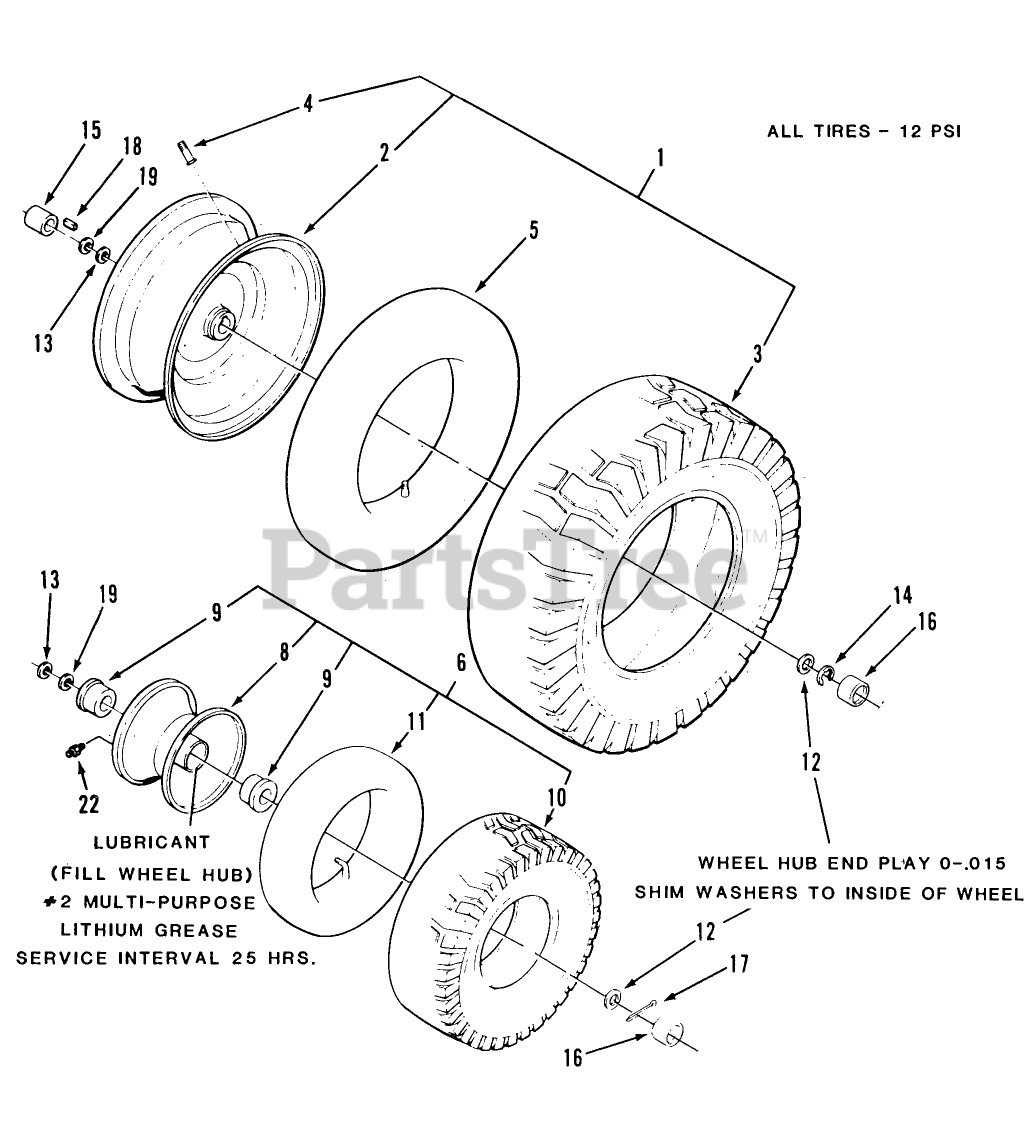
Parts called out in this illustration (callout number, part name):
4	VALVE
6	ASSY-WHEEL TIRE
8	ASS'Y-WHEEL
9	BUSHING-FLANGE
12	WASHER-FLAT
13	WASHER
15	LH AXLE SPACER
18	SQ KEY
19	WASHER-SHIM
